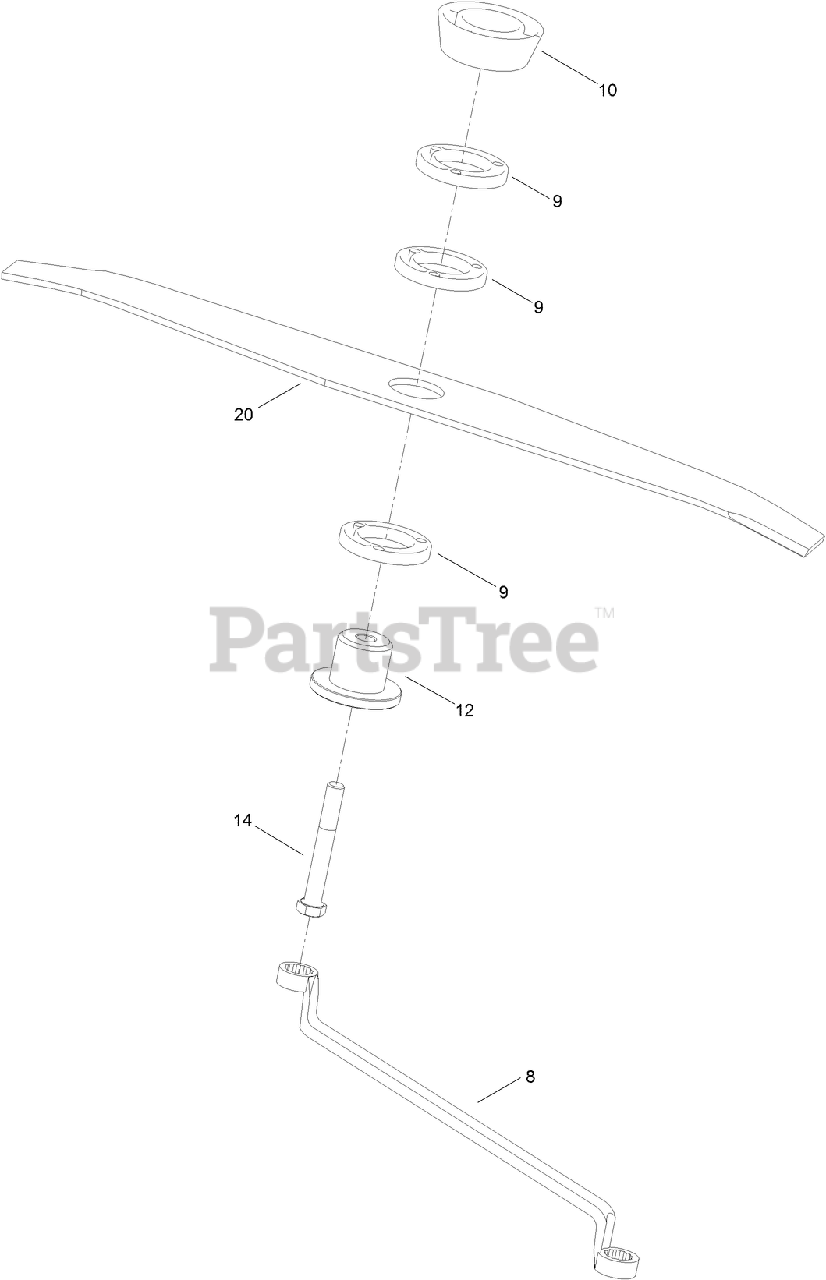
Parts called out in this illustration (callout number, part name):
8	SPANNER
9	SPACER-BLADE, ALUMINIUM
10	SPACER-DISTANCE
12	RETAINER-BLADE
14	SCREW-SET
20	BLADE (50 CM)
